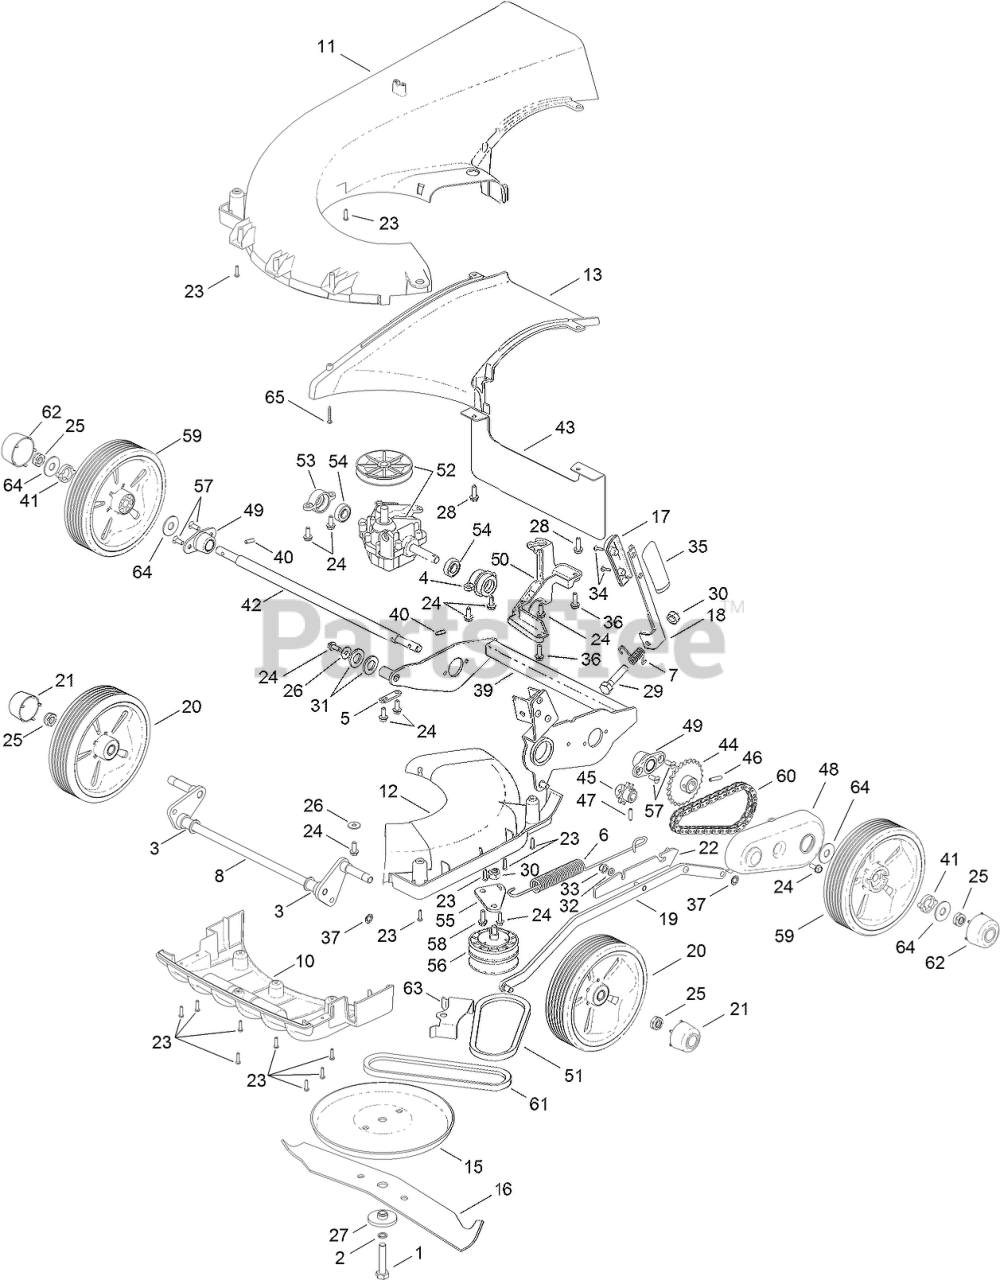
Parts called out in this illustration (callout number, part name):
1	BOLT-UNF
2	WASHER-SPRING
3	BEARING-AXLE, FRONT
4	HOUSING-PIVOT BEARING, LH
5	PLATE-SECURING
6	SPRING-COUNTER BALANCE
7	SPRING-HOC
8	AXLE-FRONT
10	MOULDING-FIN
11	MOULDING-SNAIL DECK
12	MOULDING-ACCESS, SNAIL DECK
13	MOULDING-THROW PLATE
15	DISC-FRICTION
16	CUTTERBAR
17	KNOB-HOC, RH
18	LEVER-HOC
19	ROD-CONNECTING BAR
20	WHEEL ASM
21	CAP-WHEEL, CENTER
22	MOUNT-SPRING
24	SCREW M6 X 16 TAPTITE HEX HD
25	NUT-NYLOC
26	WASHER
27	SPACER-DISTANCE, CUTTERBAR
28	SCREW-TAPTITE
29	SCREW-HH
30	NUT-HEX, NI
31	WASHER-PLAIN
32	WASHER-SHAKEPROOF
33	NUT-NYLOC
35	KNOB-HOC, LH
36	SCREW-HH
37	WASHER-STARLOCK
39	FRAME-REAR WHEEL
40	KEY-DRIVE
41	CAM-DRIVE
42	AXLE-REAR
43	GUARD-REAR
44	SPROCKET-24T
45	SPROCKET-GEARBOX, 10T
46	PIN-SPRING, SELLOC
47	PIN-ROLL
48	COVER-DRIVE
49	HOUSING-BEARING, ROLLER
50	MOUNT-BEARING
51	BELT-VARIATOR
52	GEARBOX ASM
53	HOUSING-GEARBOX, BEARING (RH)
54	BEARING
55	BRACKET-BELT
56	PULLEY VARIATOR ASM
57	SCREW-TAPTITE
58	SCREW-TAPTITE
59	WHEEL ASSEMBLY (DRIVE, GREY)
60	CHAIN-43 LINKS
61	BELT-VARIATOR (536)
62	CAP-DRIVE WHEEL
63	GUARD-BELT
64	WASHER-THRUST
